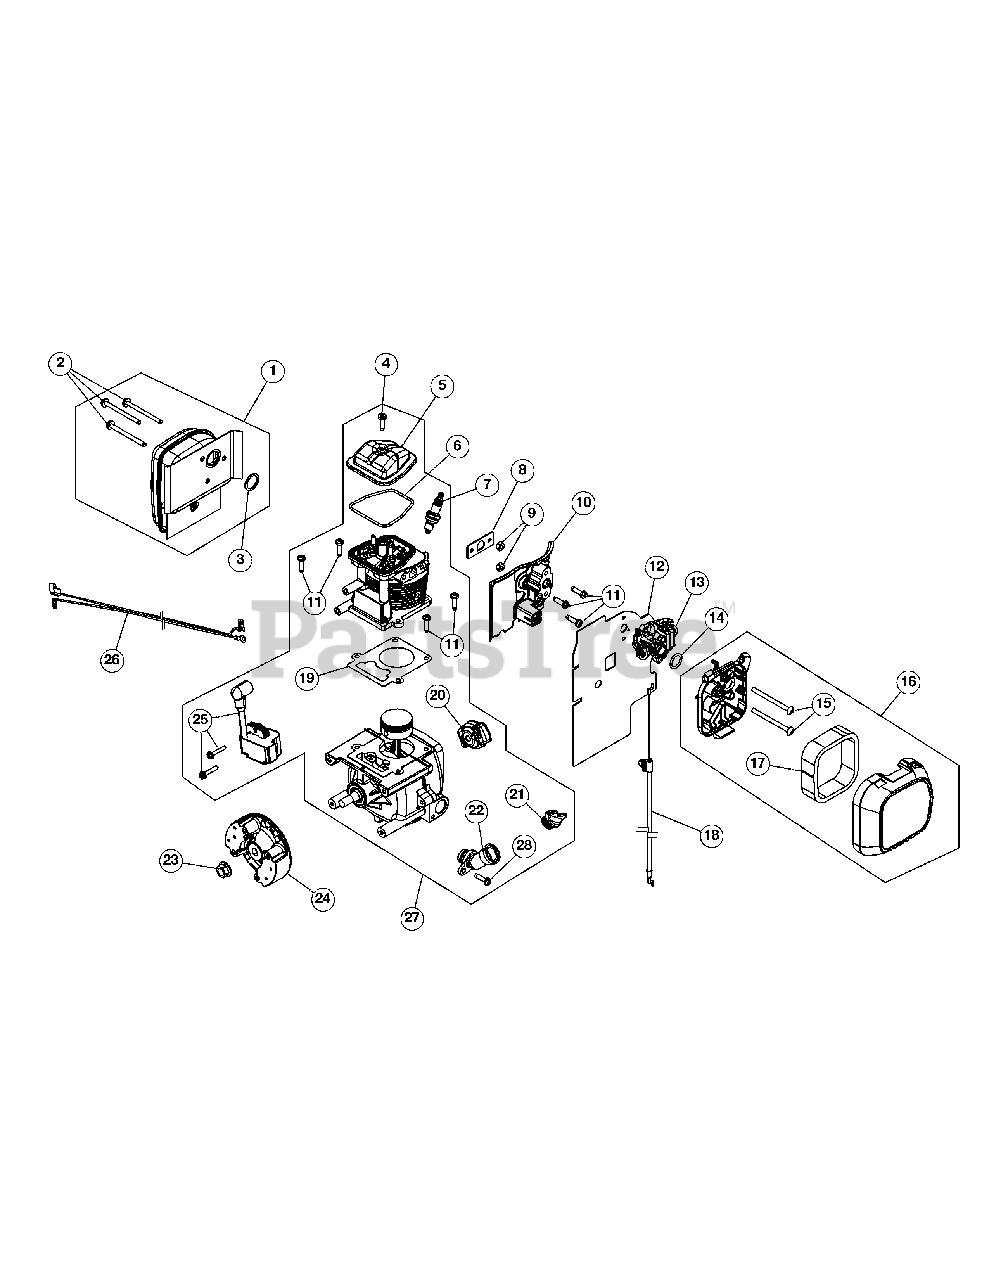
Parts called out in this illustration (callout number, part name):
1	Muffler Assembly (Incl. 2 & 3)
2	Muffler Screw
3	Muffler Gasket
5	Rocker Cover
6	Rocker Cover O-Ring
7	Spark Plug
8	Insulator Gasket
10	Insulator
11	Screw
12	Carburetor Gasket
13	Carburetor
14	Carburetor O-Ring
16	Air Cleaner Assembly (Incl. 16)
17	Air Filter
18	Throttle Cable
19	Cylinder Gasket
20	Pawl Assembly
21	Oil Plug
22	Oil Fill Tube (Incl. 3)
24	Flywheel Asssembly
25	Module Assembly
26	Lead Wire
27	Short Block Assembly
28	Screw
